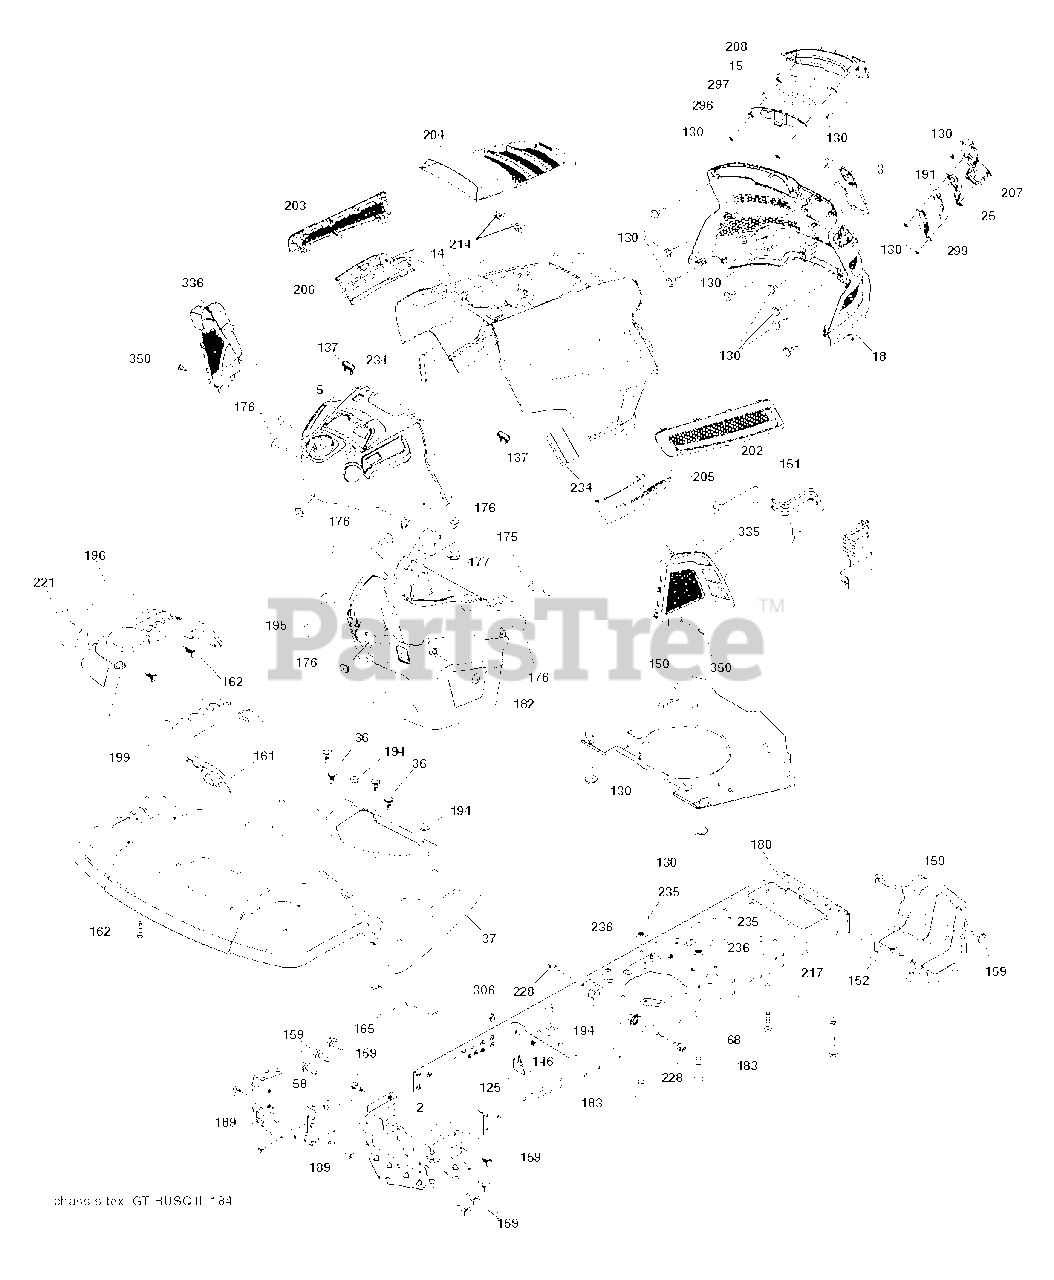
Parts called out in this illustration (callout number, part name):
2	DRAWBAR.LOWER.2PC.18/22
3	APPLIQUE.SUBASM.GT.HUSQ.II
5	DASH
14	HOOD.ASM.HUSQVARNA.GT.TEX.ORAN
15	LED LIGHT.LH
18	GRILLE SUBASM.GT.II.LOW.HDLGHT
25	LENS.RH
36	SCREW 5/16"
37	FENDER.PNT.TX.GT.CH/FW/DL.HUSQ
58	DRAWBAR.UPPER.2PC,LRG.FENDER
68	SCREW LT
125	CLIP.FUEL.LINE
130	SCREW.#10 X 0.750.BOS
137	BUMPER DASH
146	BOLT.RDHD.SHT.SQNK.3/8-16X5/8
150	AIR DUCT.GTV2(1.66"RING HEIGHT
151	BRACKET.PIVOT.HOOD.GT.HUSQ.II
152	SHIELD.BROWNING.PNT.GT.V2
159	SCREW, 3/8-16X3/4
161	CONSOLE.WINDOW.FUEL.HUSQ.GT
162	SCREW.HI-LO.CONSOLE
165	SUPPORT.TANK.REAR.B/TE
175	PLATE.CROSSMEMBER.HUSQ
176	SCREW.#10-24X5/8.RN.QU
177	BUSHING STEERING
180	CHASSIS.TEX.BOLTED
182	DASH.LOWER.COMMON.12V.ADAPTOR
183	BOLT.5/16-18X1-1/4 FULL THD
189	SCREW
191	INSERT INFLECT.RH
194	NUT LOCK HEX FLANGE 5/16-18
195	PLUG.HOLE.DASH.LOWER.12V.BLK
196	SUBASM.CONSOLE.HUSQ.GT.DECKLFT
199	PLATE.DECK.LIFT.HUSQVARNA.GT
202	VENT.SIDE.RH.GT.HUSQ.II.
203	VENT.SIDE.LH.GT.HUSQ.II.498
204	VENT.TOP.ASM.HUSQ.GT2
205	SIDE.TRIM.RH.GT.HUSQ.II
206	SIDE.TRIM.LH.GT.HUSQ.II.GRAY
207	BEZEL GT2 LED RH W/ LOWER.ATT
208	BEZEL GT2 LED LH W/ LOWER ATT
214	CLIP.RETAINER.TINNER.
217	ROD.PIVOT.HOOD
221	REFLECTOR.LH.TEX GT HU
228	STUD.FASTNER.W/ANTI-ROTATE
234	BUMPER.HOOD.TEX.HUSQVARNA
235	SPACER FENDER
236	NUT.CENTERLOCK.5/16-
296	LED LIGHT.LH
297	INSERT REFECT LH
299	LED LIGHT.RH
306	NUT LOCK FLG 3/8-16 UNC
335	COVER.LOWER.DASH.RH.BLACK
336	COVER-LH.LOWER.DASH.GT2.BLACK
350	CLIP.X-MAS.TREE
